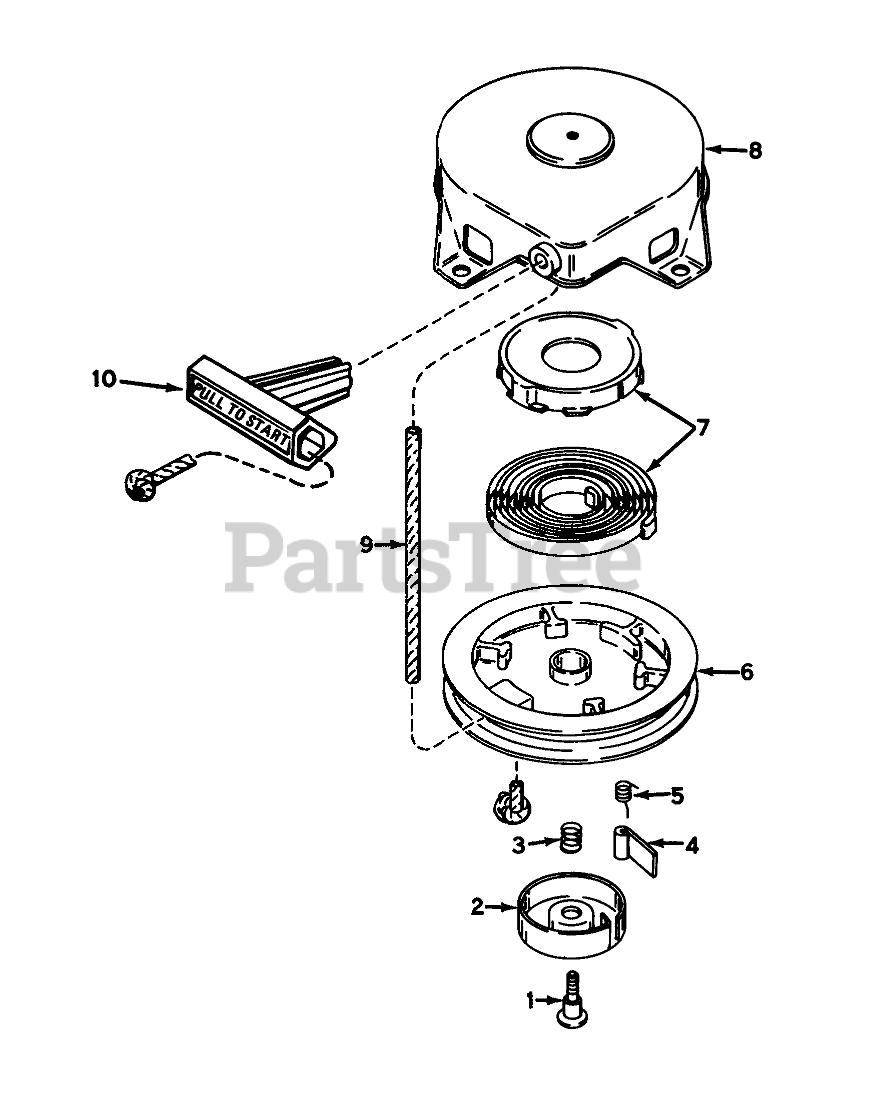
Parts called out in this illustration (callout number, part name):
2	Retainer
3	Spring-Brake
4	Dog-Starter
5	Spring-Dog
7	Spring & Keeper Assy
8	Housing-Starter
9	Rope-Starter (98 cut to length)
10	Handle-Starter
